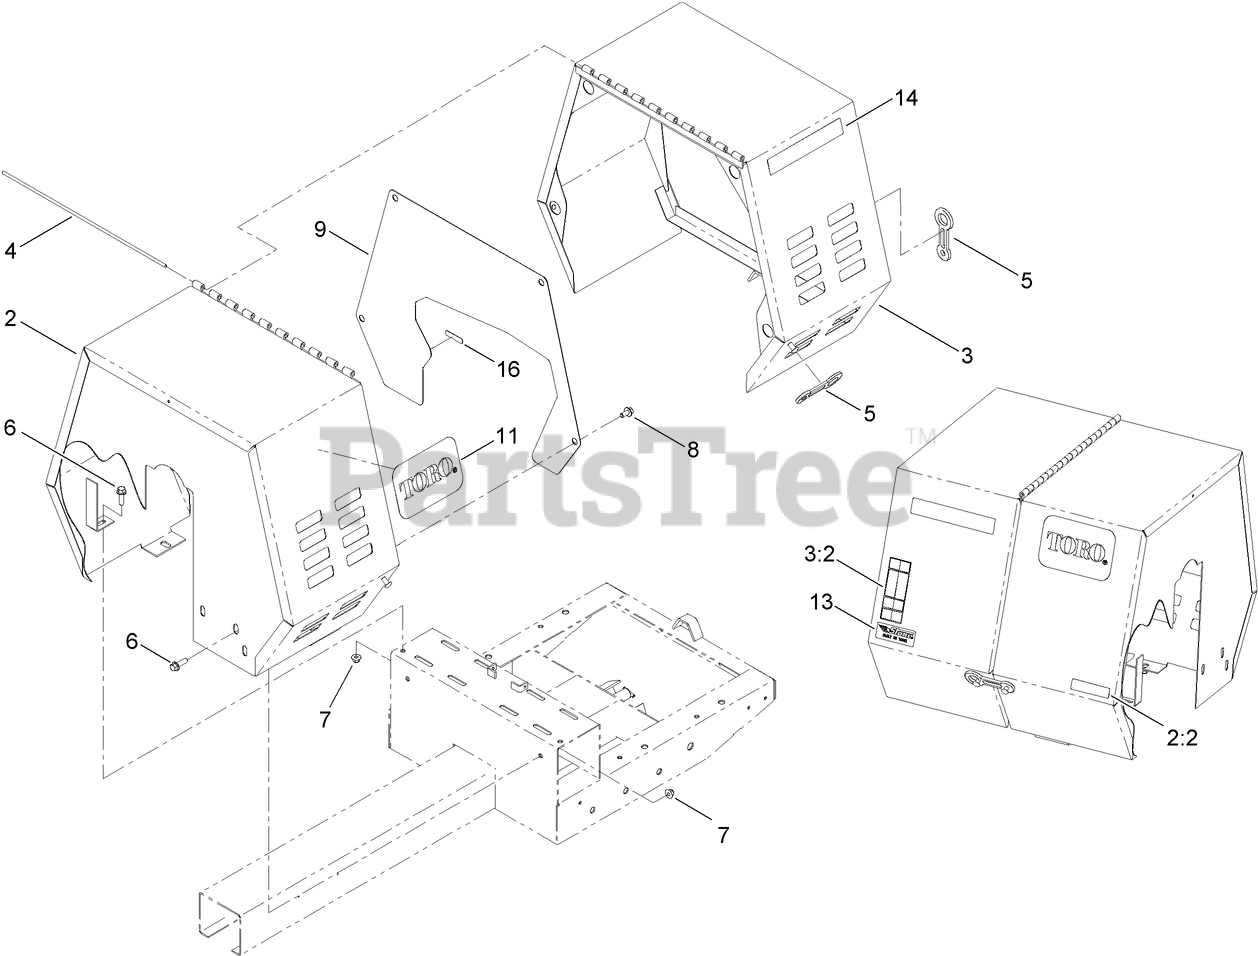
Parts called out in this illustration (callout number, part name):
2	STATIONARY COWL ASM
2:2	DECAL-ARRESTER, SPARK
3	MOVABLE COWL ASM
3:2	DECAL-WARNING
5	LATCH-RUBBER
6	SCREW-HHF
7	NUT-HF, NI
8	SCREW-HWH
9	PLATE-ACCESS, BELT
11	DECAL
16	DECAL-GREASE
